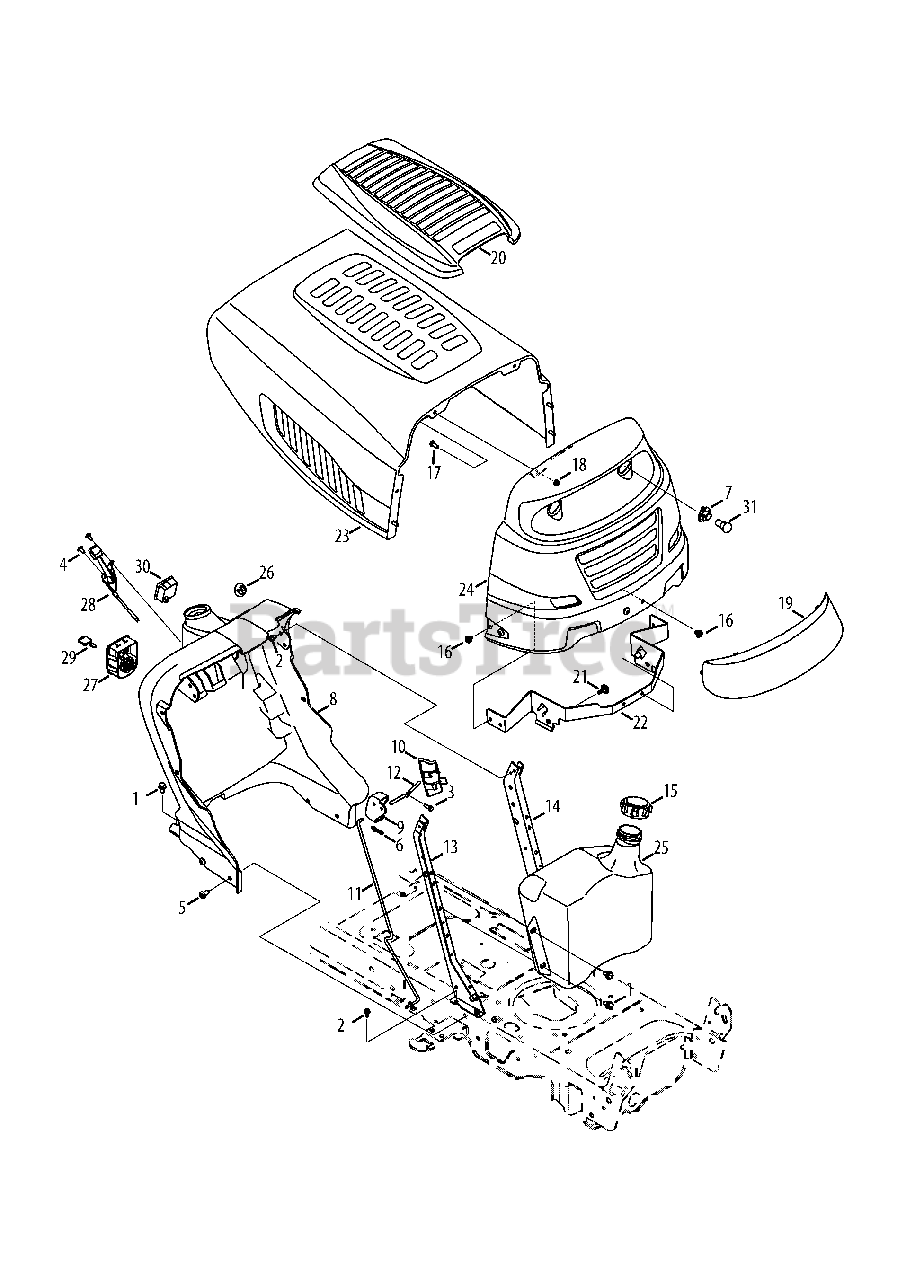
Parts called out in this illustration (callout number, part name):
1	Taptite Screw ,5/16-18:.750
2	Taptite Screw ,1/4-20:0.500
3	Hi-Lo Screw, 1/4-15:0.750
4	Screw, 1/4-14:0.625
5	Taptite Screw ,5/16-18:0.750
6	Bow Tie Cotter Pin
7	Lamp Socket
8	Dash Panel, No Sight Window
9	Dash Lever
10	Cruise Cover
11	Control Rod
12	Lever
13	RH Support Plate
14	LH Support Plate
15	Fuel Cap, EPA
16	Taptite Screw ,5/16-18:0.375
17	Hex Screw, 1/4-20:.620
18	Flangelock Nut, 1/4-20
19	Grill Lens
20	Hood Scoop
21	Shoulder Screw, .43X.29:5/16-18
22	Hood Pivot Bracket
24	Grill
25	Fuel Tank, EPA
26	Choke Plug
27	Key Switch Module
28	Throttle/Choke Control
29	Key, Assembly
30	Hour Meter
